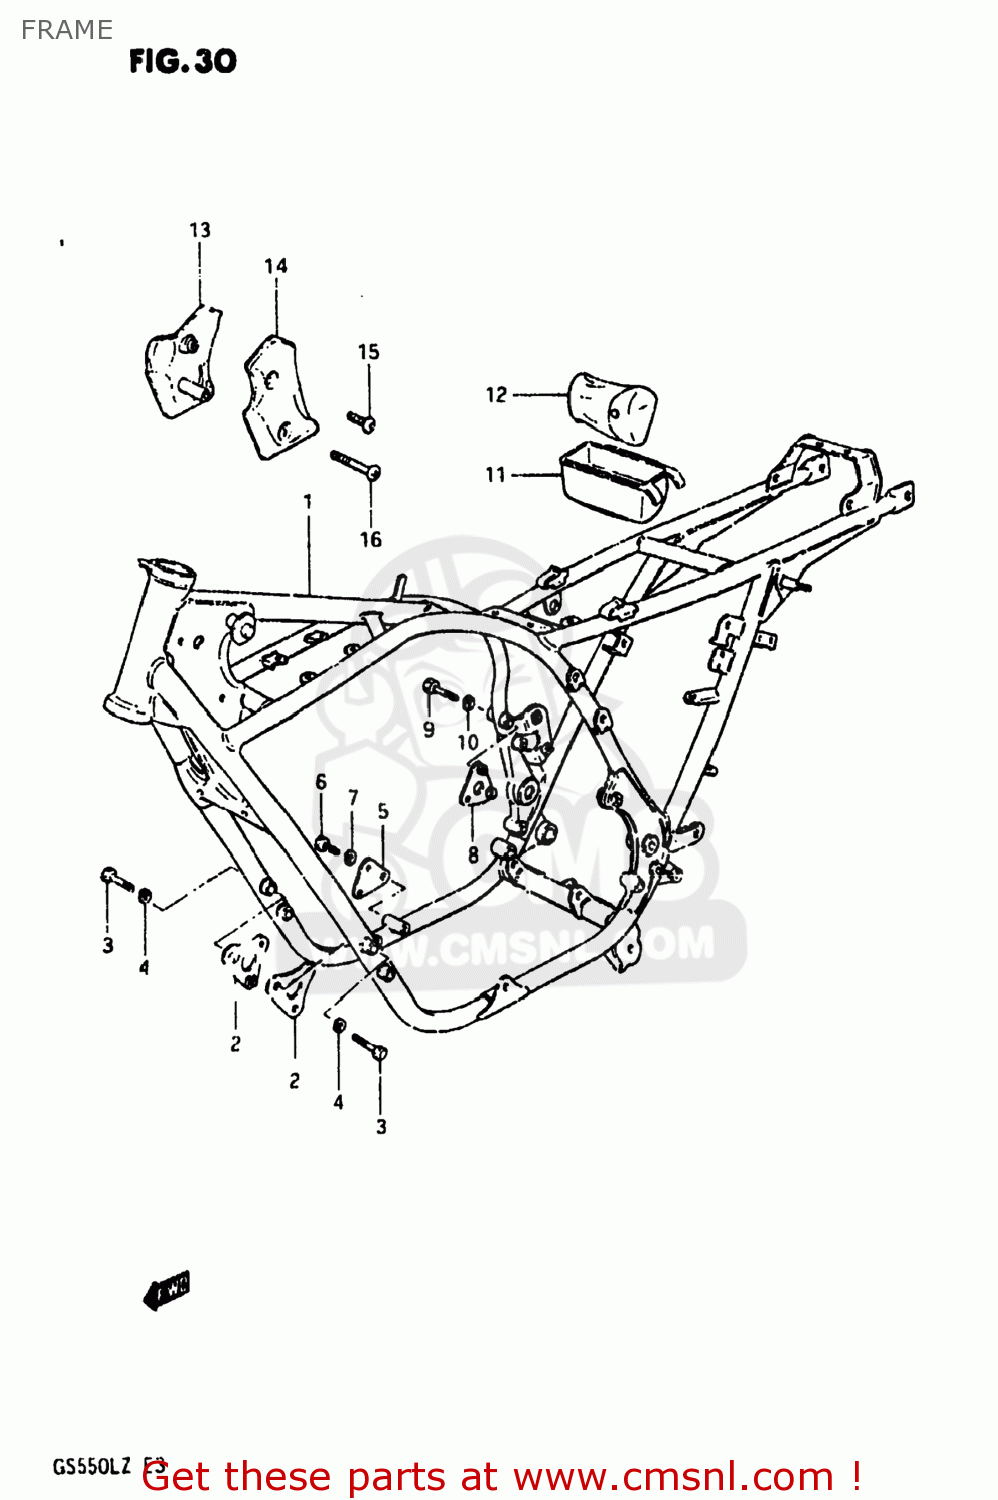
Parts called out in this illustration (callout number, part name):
1	FRAME
2	PLATE,ENGINE MOUNTING
3	BOLT
4	LOCK WASHER
5	PLATE,ENGINE MOUNTING
6	BOLT
7	LOCK WASHER
8	PLATE,ENGINE MOUNTING
9	BOLT 8X55
10	LOCK WASHER
11	HOLDER,TOOL
12	TOOL SET
13	COVER,FRAME HEAD,RIGHT
14	COVER,FRAME HEAD,LEFT
15	SCREW
16	SCREW, LOWER
